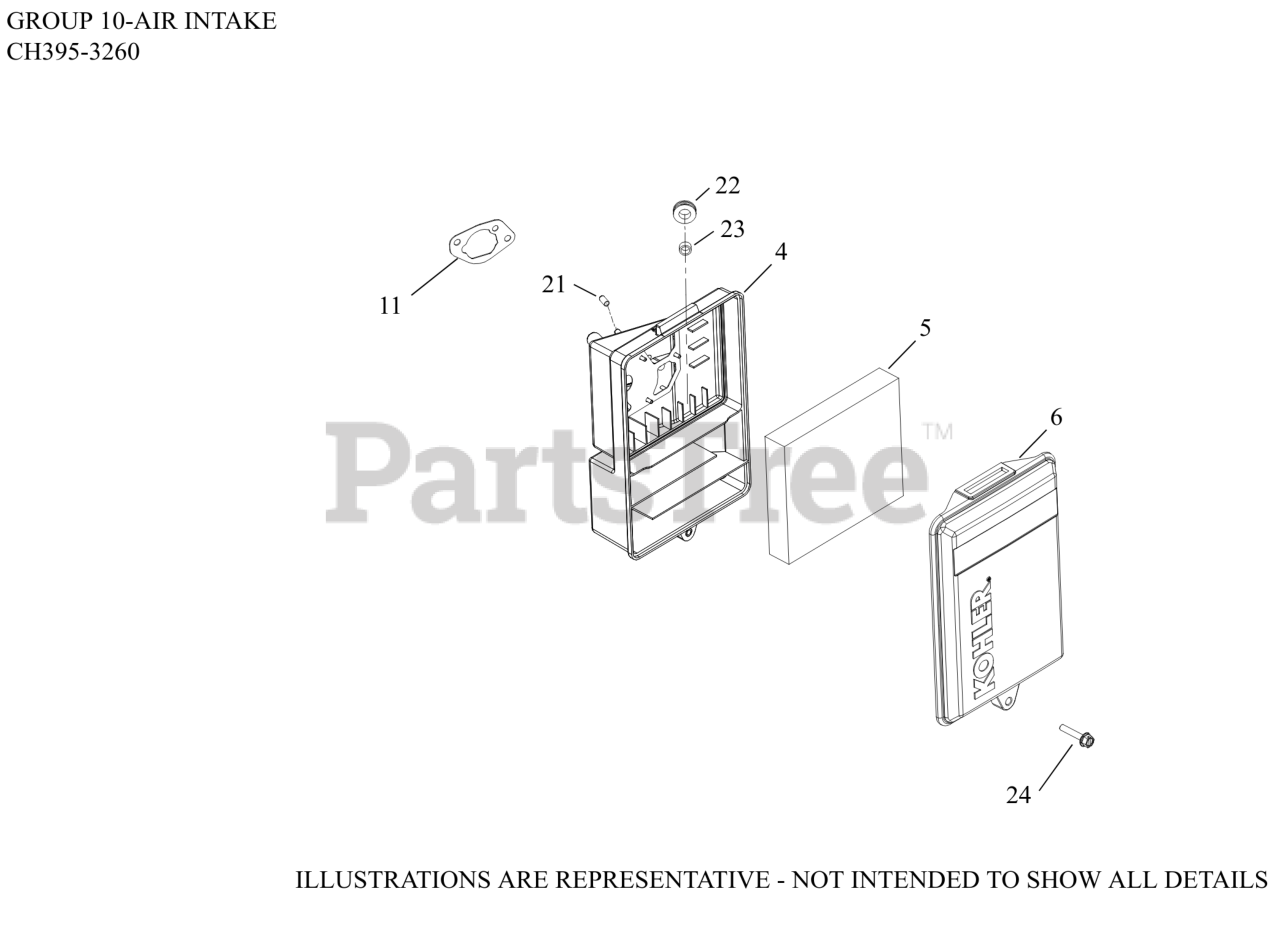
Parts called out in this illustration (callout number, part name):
4	BASE ASSEMBLY, AIR CLEANER
5	ELEMENT, AIR FILTER
6	COVER, AIR CLEANER
11	GASKET, AIR CLEANER
21	CAP, MASKING (CKY)
22	ISOLATOR, VIBRATION
24	SCREW, HEX FLANGE SLOTTED (M6)
